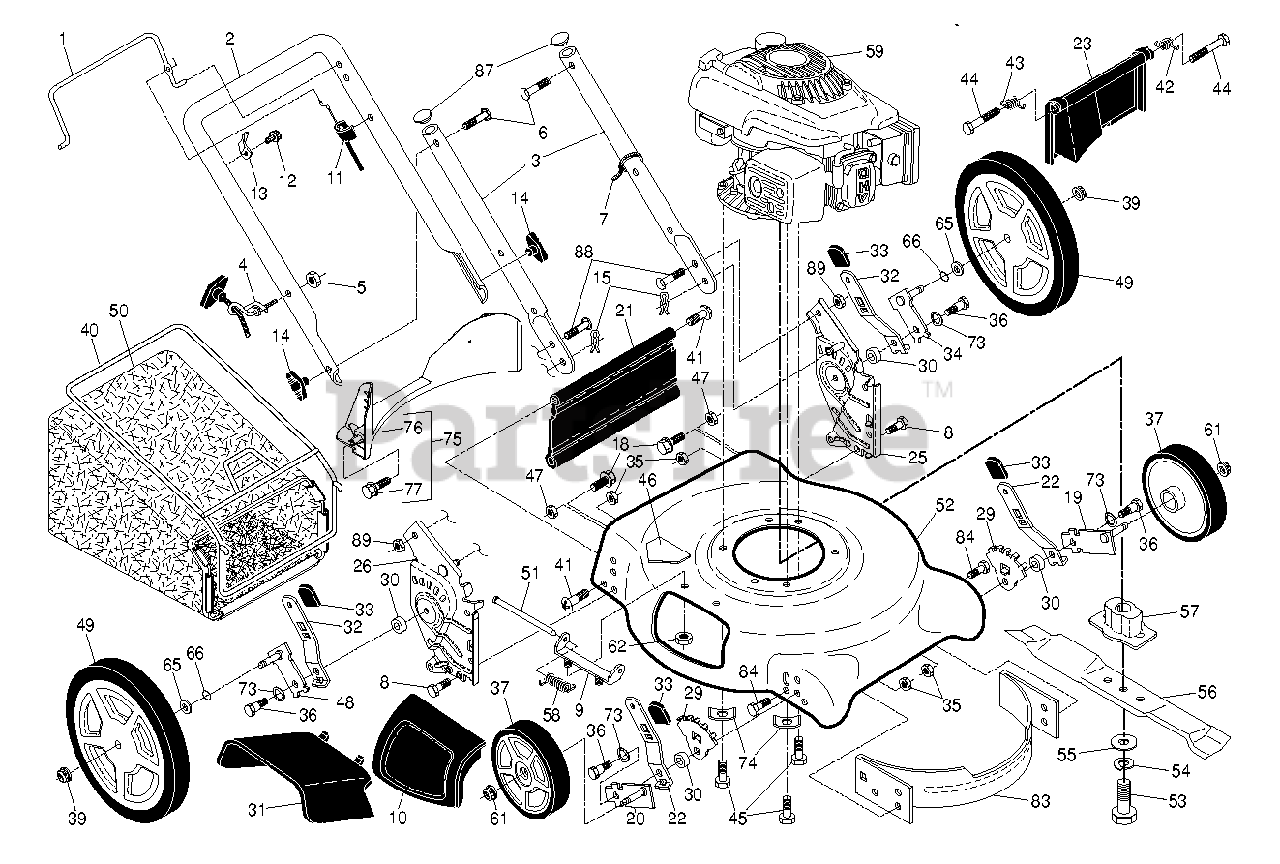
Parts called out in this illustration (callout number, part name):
1	BAIL.CONT.D.STRAIGHT.PUSH.BLK
2	HANDLE.UPPER.ECONOMY.BLACK
3	HANDLE.LOWER.DOME.BT.BLACK
4	Rope Guide, Blk Zinc Chrom
5	T-KNOB.NEW ROPE GUIDE
6	BOLT, HANDLE 5/16-18X1.75
7	TIE GUIDE
8	BOLT
9	BRACKET.ASM.HOUSING.EZ.MUL
10	MULCH DOOR
11	CABLE.MZR.RATO.22"LOW.
13	BRACKET.UPSTOP.RT
15	HAIRPIN COTTER
18	SCREW 1/4X20
19	AXLE ARM ASSY FRONT LH
20	AXLE ARM ASSY FRONT RH
21	KIT.SKIRT.21 DOMED.W/LIP
22	SELECTOR SPRING, FRONT
23	REAR DOOR ASSY
25	BRACKET.ASM.HANDLE.HW.21.LT.BL
26	BRACKET.ASM.HANDLE.HW.21.RT.BL
29	WHEEL ADJ BRACKET FRONT
30	SPACER.HEIGHT.ADJUSTER
31	CLIP ON DISCHARGE GUARD
32	SPRING.SEL.22.ECON.HI-WHL.RATO
34	Axle Arm Assembly, .Lr.5/9.Pos.Bzp
35	NUT.FLANGE.HEX.5/16X18.BLACK
36	SHOULDER BOLT 5/16-18
37	WHEEL.8X1.75.5.SPK.BRK.BLK.1
39	NUT.HEX.FLANGE.3/8-16.LOCKNUT
40	FRAME.BAG.21.REAR.DOMED.PUSH
41	SCREW.1/4-20X21/4.HEX.
42	SPRING.LH.22.REAR.DOOR.EZ.EMPT
43	SPRING.RH.22.REAR.DOOR.EZ.
45	BOLT 3/8-16X1-1/8
46	No Step Decal
47	NUT.LOCK.5/16-18
48	Axle Arm Assembly, RR 5/9 Pos BZP
49	WHEEL.12X1.75.5SPK.BRK.BLACK
50	GBAG.24710612.BLK.WEAT
51	ROD.HINGE.COMBI-C
53	SCREW, HEX HD 3/8-24 X 1-3/8
55	WASHER,HARDEN
56	BLADE.21.PUSH/RWGD/FWGD
57	ADAPTOR.BLADE.7/8
58	TORSION SPRING
61	NUT.HEX.FLANGE.3/8-16.LOCKNUT
62	LOCKNUT.NYLOC.1/4-20
65	WASHER PM
66	O-RING..070X.487.NEOPRENE
73	WASHER.CURVED.CYLINDRICAL
74	WASHER.ENGINE.BZP
75	KIT.BAFFLE.REAR.PLASTIC.21.RD
76	BAFFLE.REAR.PLASTIC.21.RD.ECON
77	SCREW.HX.13X.750
83	BAFFLE.FRONT.21.DOME.US
84	BOLT.5/16HEX.WHS.HD
87	PLUG.PLASTIC.7/8".14-20.GAUGE
89	LOCKNUT-FLANGE 5/16-18
